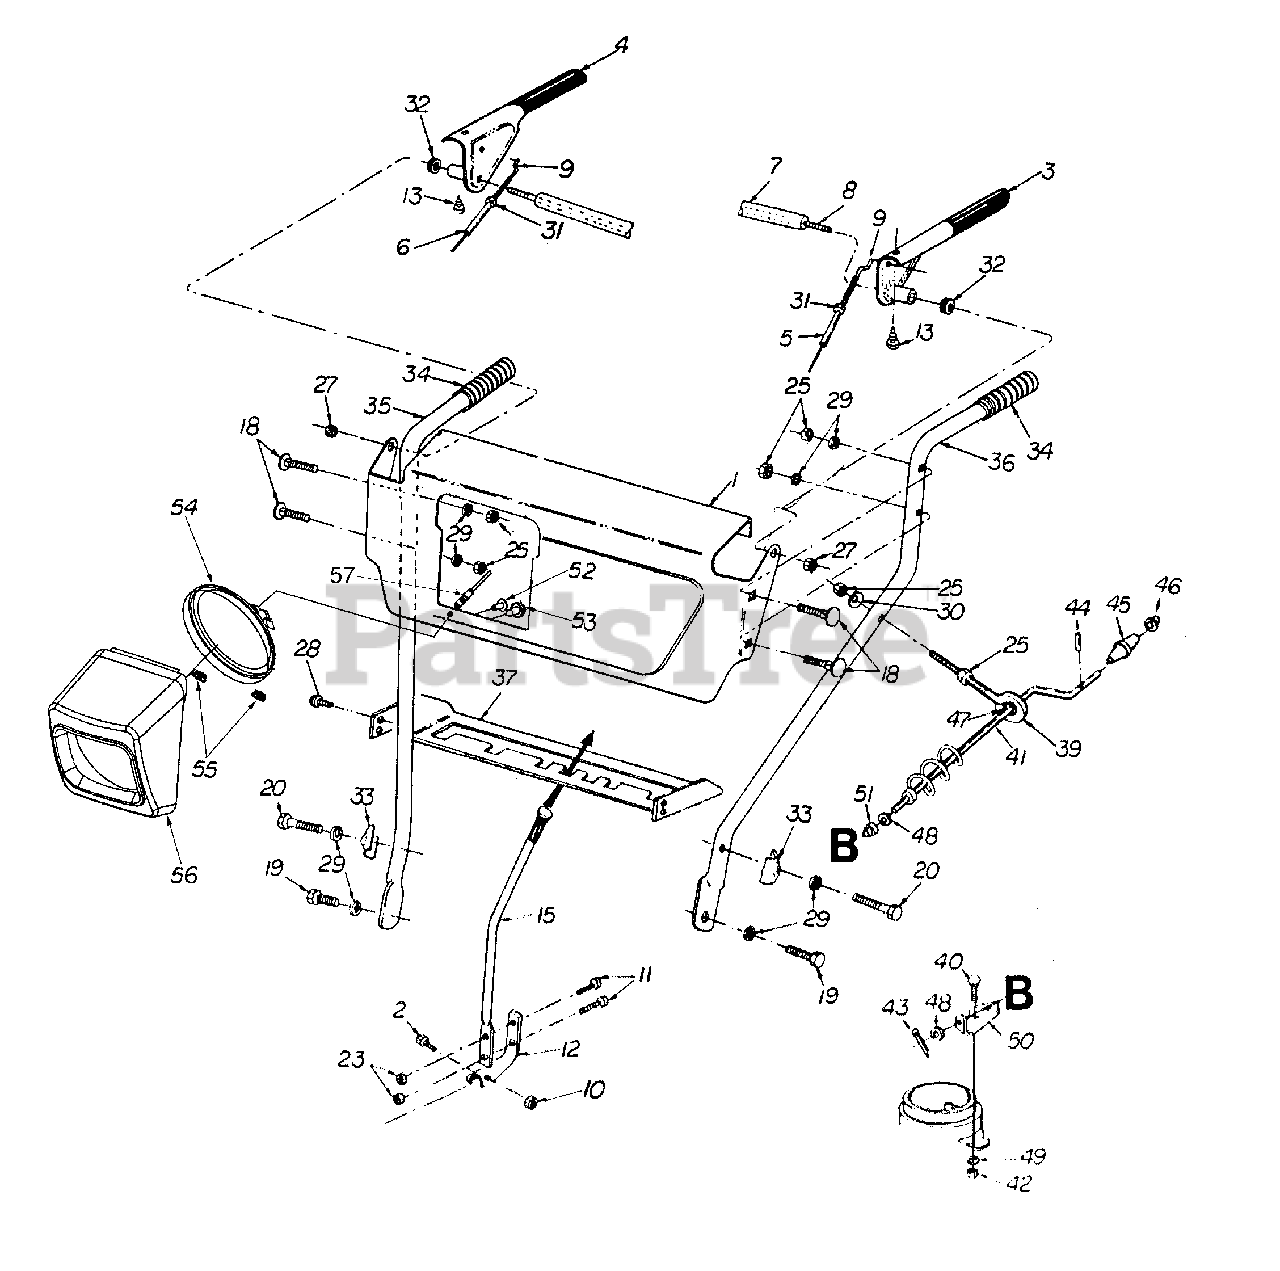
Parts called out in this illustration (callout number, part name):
2	Hex Bolt 1/4-20 x 1.00
3	Clutch Lever LH
4	Clutch Lever RH
5	Auger Clutch Cable
6	Drive Clutch Cable
7	Pivot Rod Cover Tube
8	Clutch Lever Pivot Rod
9	"Z" Fitting
10	Hex Nut 1/4-20
11	Hex Scr. 1/4-20 x .75
12	Shift Lever Spring
13	Rubber Bumper
15	Shift Handle (w/grip)
18	Carriage Bolt 5/16-18 x 1.50
19	Hex Bolt 5/16-18 x .75
20	Hex Bolt 5/16-18 x 1.75
23	Hex Ins. L-Nut 1/4-20
25	Hex Cent. L-Nut 5/16-18
27	Hex Ins. L-Nut 5/16-18
28	Hex Wash Hd B-Tapp Scr. 1/4-20 x .50
29	L-Wash 5/16 ID
30	Bell. Washer .345 ID x .88 OD x .06
31	Hex Nut 10-24
32	Spacer
33	Handle Tab
39	Eyebolt Chute Crank
40	Carriage Bolt 5/16-18 x .75
41	Chute Crank Ass'y
42	Hex Center L-Nut 5/16-18
43	Int. Cotter Pin 5/16 Dia.
44	Roll Pin .125 Dia. x .62
45	Knob-Chute Crank
46	Cap Speed Nut 3/8
47	Grommet
48	Flat Washer .385 ID x .62 OD
49	Flat Washer .344 ID x .875 OD
51	Plastic Bushing .380 ID
52	Truss Machine Tapp Scr.
53	Scr:AB:1/4-14:.625: Hxindwsh
54	Headlight 18 Watts
55	Hex Nut .250
56	Headlight Bezel #8
57	Harness (Round Light)
